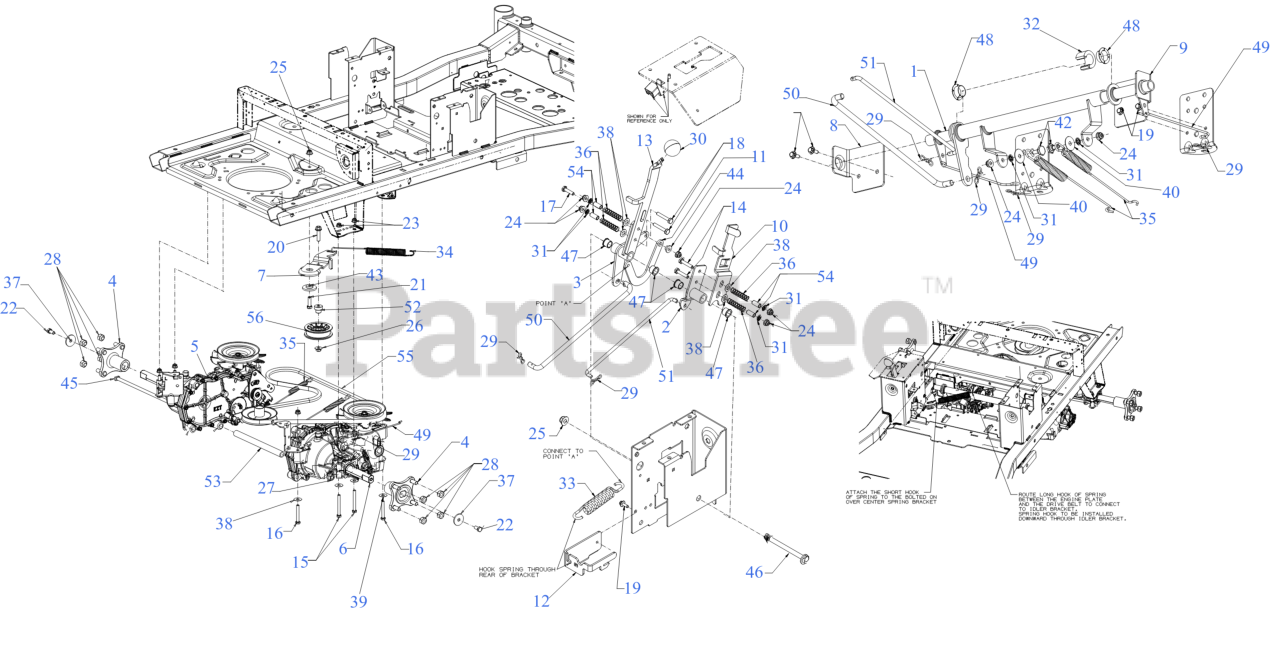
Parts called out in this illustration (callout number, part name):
1	BRAKE PIVOT SHAFT
2	BYPASS LEVER PIVOT ARM
3	PARK BRAKE PIVOT ARM
4	WHEEL HUB ASSEMBLY
4	STUD 7/16-14 x 1.6
5	TRANSMISSION (LH)
6	TRANSMISSION (RH)
7	HYDRO DRIVE IDLER BRACKET
8	BRAKE SHAFT SUPPORT (RH)
9	BRAKE SHAFT SUPPORT (LH)
10	TRANSMISSION BYPASS LEVER
11	OVER CENTER LINK
12	SPRING MOUNTING BRACKET
13	PARK BRAKE LEVER
14	HEX SCREW 1/4-20 x 1.25
15	HEX SCREW 5/16-18 x 2.75
16	HEX SCREW 5/16-18 x 2.25 GR5
17	SCREW 1/4-20 X1.00 GR5
18	SCREW 1/4-20 x 1.50 GR.5
19	SCREW M6-1 x .625
20	HEX HEAD BOLT (3/8-16:1.50 GR8)
21	SCREW 3/8-16 x 1.25 GR5
22	SCREW 3/8-16 x .75 GR 5
23	FLANGE LOCK NUT 5/16-18
24	FLANGE LOCK NUT
26	FLANGE LOCK NUT
27	FLANGE LOCK NUT
28	LUG NUT 7/16-14
29	BOW TIE COTTER PIN 1/4-5/16
30	PARK BRAKE BALL KNOB
31	RETAINER-BOLT .25ID x .50OD
32	SPACER: .76ID x .75
33	EXTENSION SPRING .57 x 5.38
34	EXTENSION SPRING .75 DIA X 10.27
35	EXTENSION SPRING .60 DIAx8.69
36	COMPRESSION SPRING
37	FLAT WASHER .390x1.500x.134
38	WASHER THRUST .375X.70X.030
39	FLAT WASHER
40	FLAT WASHER
42	SHOULDER SCREW
43	SHOULDER SPACER
44	SHOULDER SPACER
45	SUPPORT TUBE ROD
46	SHOULDER SCREW .491x3.937 3/8-16
47	FLANGE BUSHING
48	FLANGE BEARING .75 x 1.125 x .375
49	HYDRO BYPASS ROD
50	BRAKE LINK
51	BYPASS LINK
52	SHOULDER SPACER
53	SUPPORT TUBE
54	SPACER .252x.350x.760
55	TRANSMISSION DRIVE BELT A x 67
55	Cub Cadet TRANS DRIVE BELT A x 67 RZT
55	Troy-Bilt TRANSMISSION DRIVE BELT
56	FLAT IDLER PULLEY 3.00 OD
